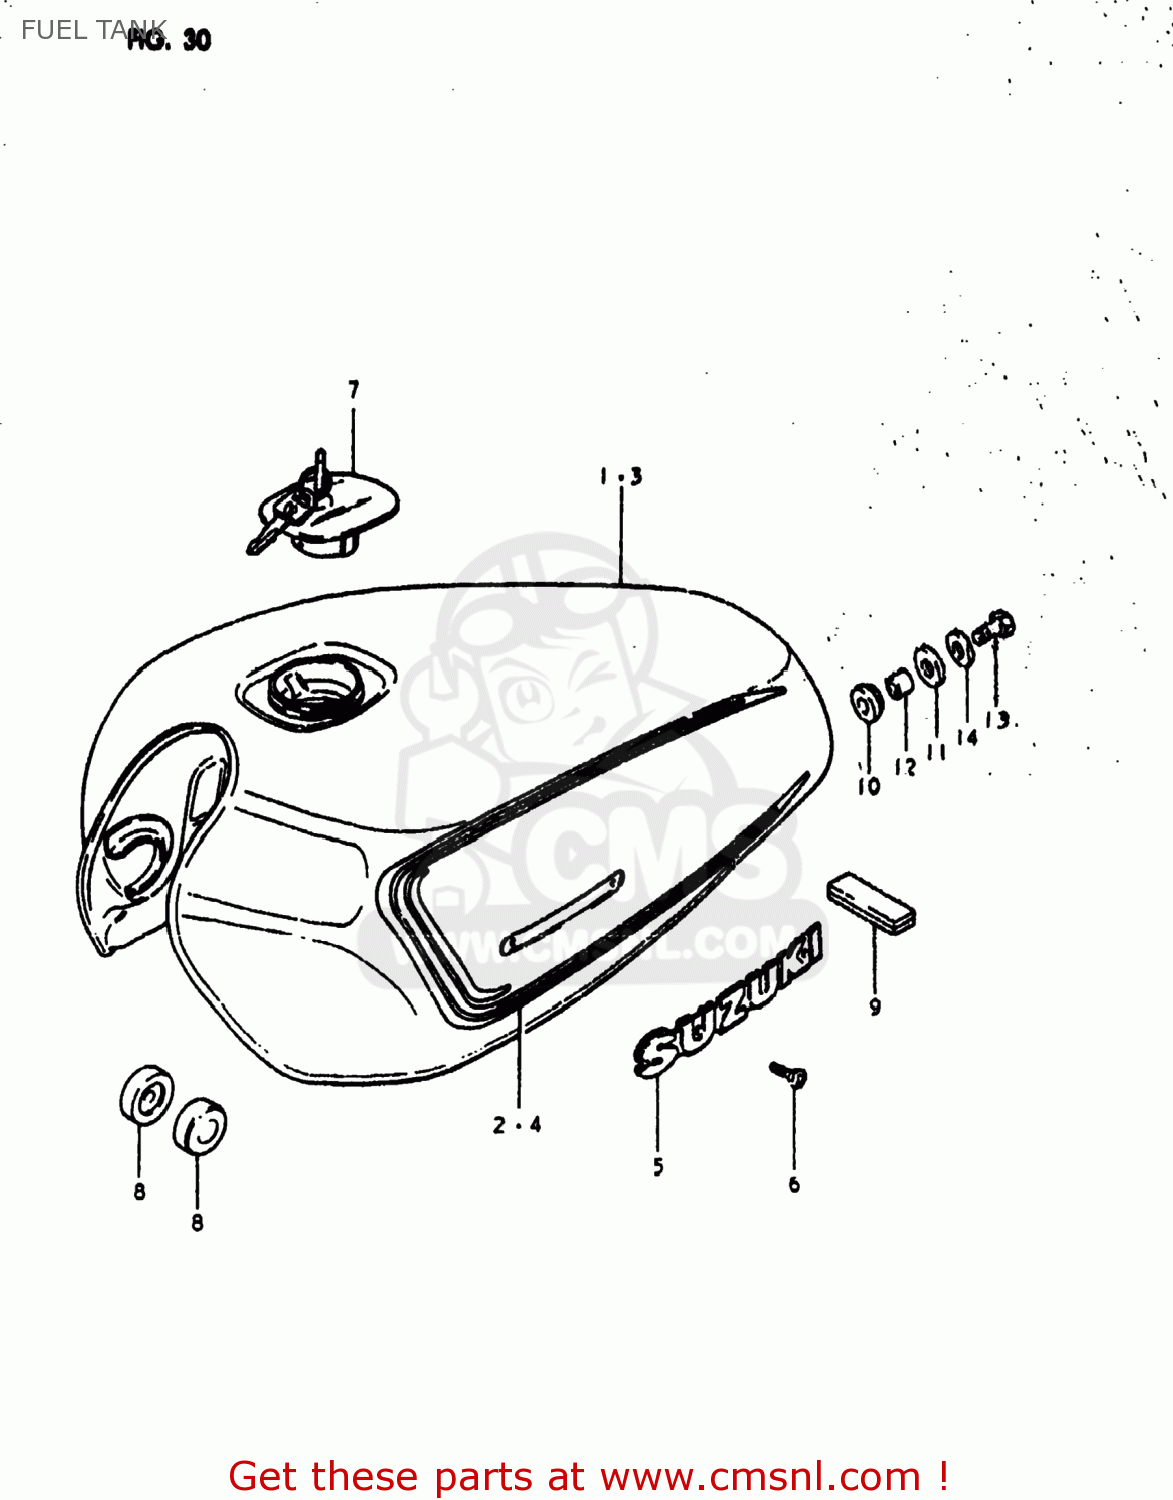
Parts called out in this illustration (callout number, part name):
1	TANK ASSEMBLY,FUEL
2	TAPE SET,FUEL TANK
3	TANK ASSEMBLY,FUEL
4	TAPE SET,FUEL TANK
5	EMBLEM
6	SCREW 3X6
7	CAP SET,FUEL TANK
8	CUSHION
9	CUSHION
10	CUSHION
11	CUSHION
12	SPACER(8.5X12X19)
13	BOLT (8X30)
14	WASHER (8.5X29X1.6)
